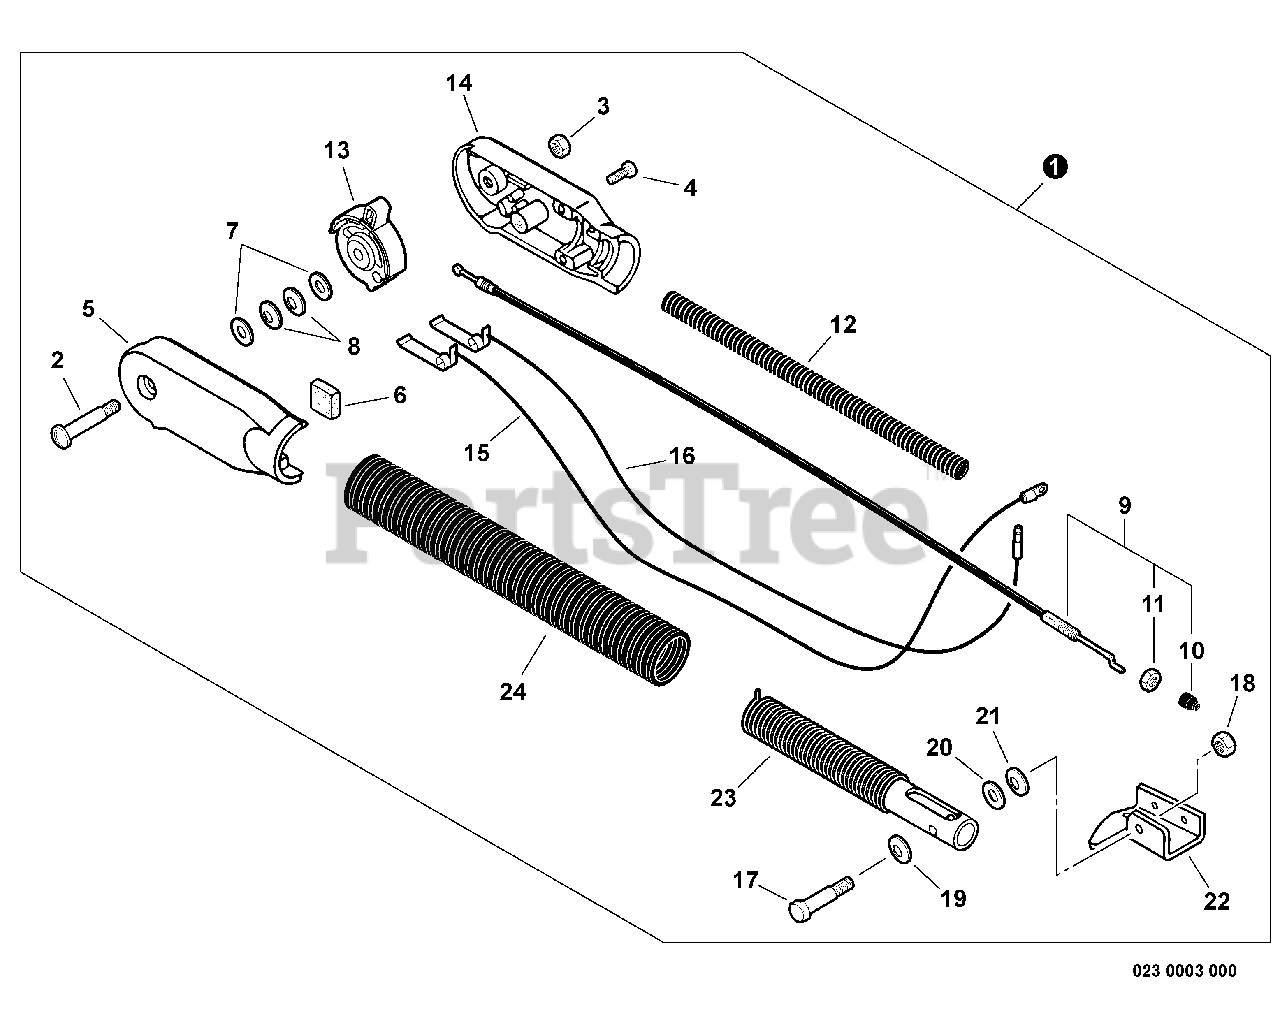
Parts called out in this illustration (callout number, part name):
1	THROTTLE CONTROL KIT - HIP MOUNT
3	NUT, LOCK 4
5	GRIP, LEFT THROTTLE
6	PAD, FOAM
7	WASHER 6.5×15.5×0.6
8	WASHER, FRICTION 6.6×14.3
9	THROTTLE CABLE ASSY
10	CAP, DUST
11	NUT, HEX M6
12	TUBE, PROTECTIVE - CORRUGATED
13	LEVER, THROTTLE
14	GRIP, RIGHT THROTTLE
16	LEAD - IGNITION
19	WASHER, WAVE
20	WASHER 8
21	WASHER 8
23	SPRING TUBE ASSY
24	TUBE, OUTER
